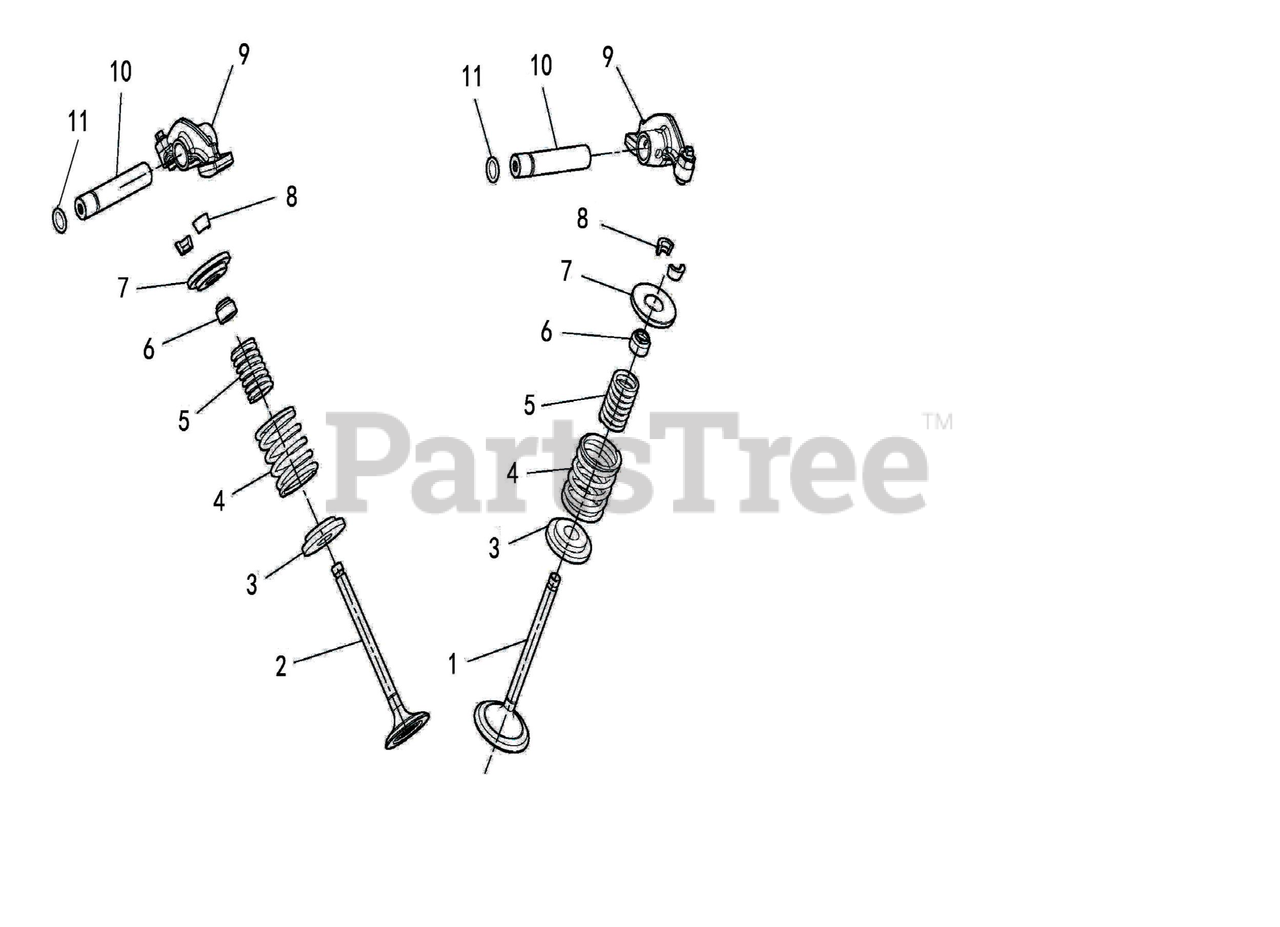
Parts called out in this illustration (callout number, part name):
1	INTAKE VALVE
2	EXHAUST VALVE
3	VALVE SPRING WASHER
4	VALVE OUTER SPRING
5	VALVE INNER SPRING
6	VALVE STEM SEAL
7	RETAINER VALVE SPRING
8	VALVE COLLAR
9	ROCKER ARM ASSEMBLY
10	VALVE ROCKER SHAFT
11	O-Ring 9X2
